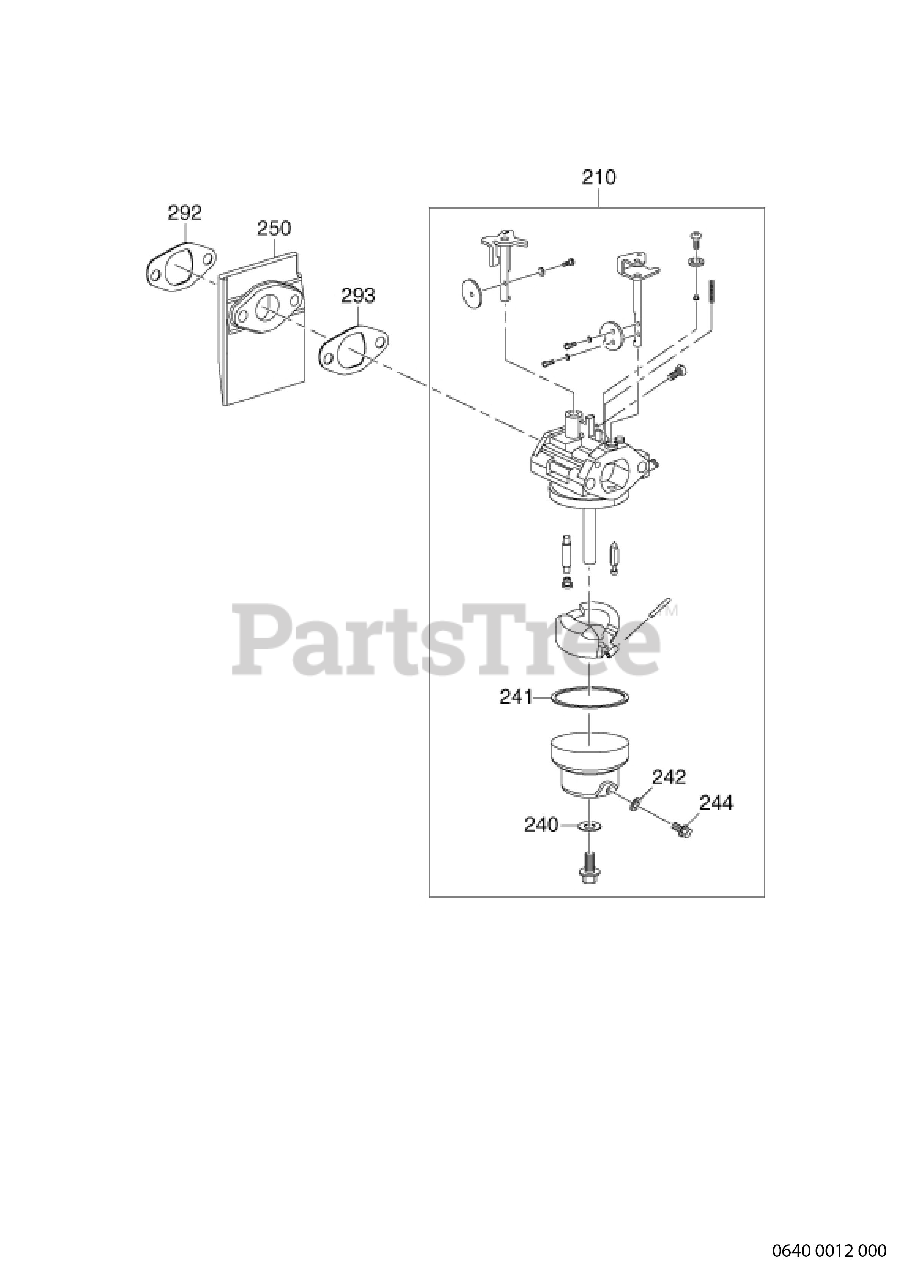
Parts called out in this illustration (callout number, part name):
210	CARBURETOR ASSY CCC
241	O-RING,FUEL CUP
242	PACKING,DRAIN BOLT
292	INSULATOR GASKET
293	CARBURETOR GASKET
